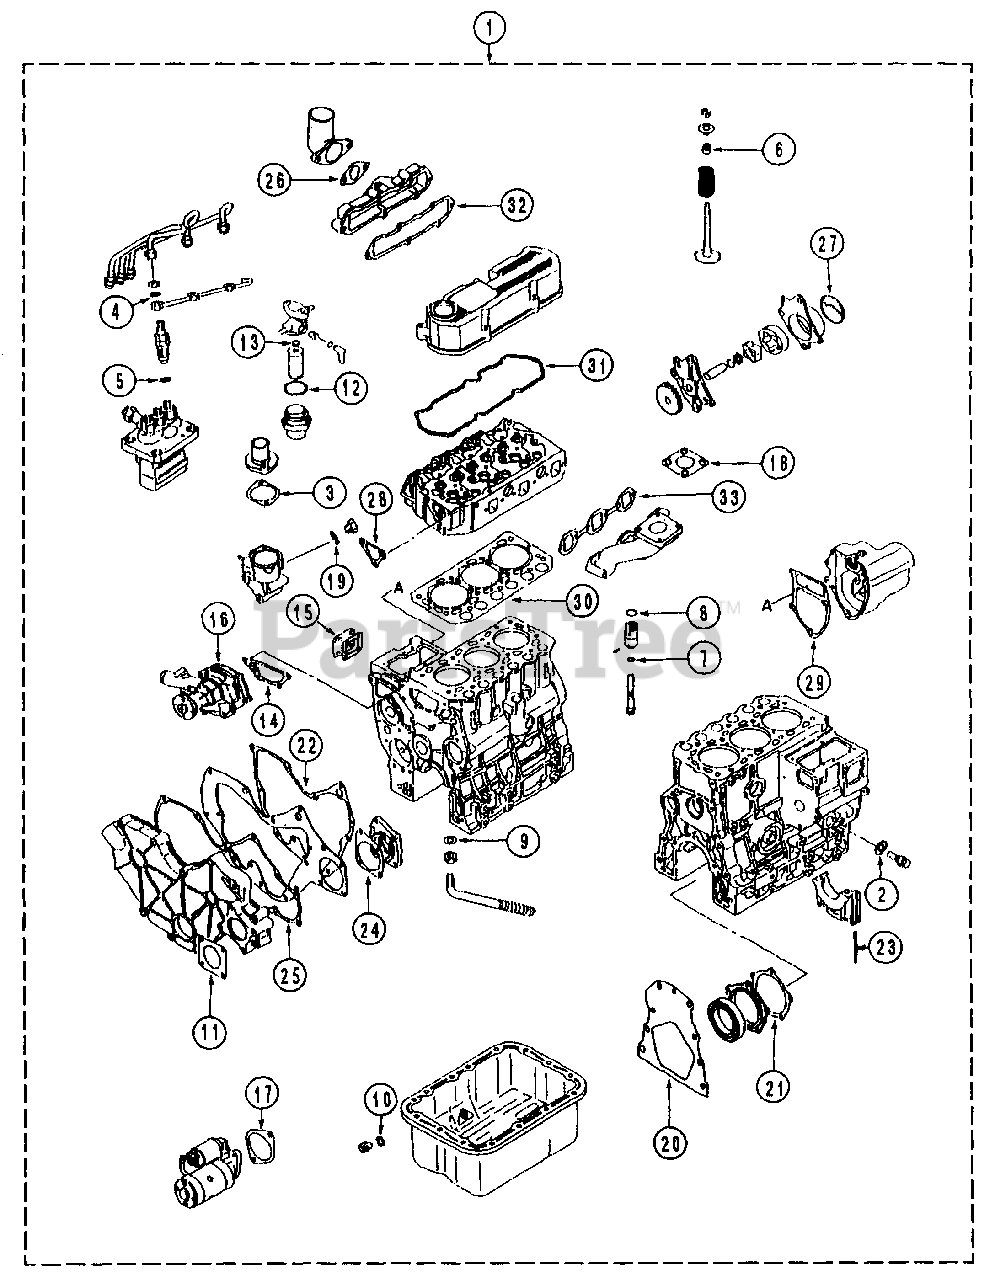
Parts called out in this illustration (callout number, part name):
1	Gasket Kit, (O/H)
3	Gasket
6	Seal, Valve Stem
8	O-Ring
11	Gasket, O/Pump Cover
12	O-Ring
13	O-Ring
14	Gasket, Water Pump
15	Gasket, Tie-Rod Cover
16	Gasket, Water Pump
17	Gasket, Starter
20	Gasket, Rear Plate
21	Gasket, Oil Seal Case
22	Gasket, Front Plate
24	Gasket, Housing
25	Gasket, Gear
26	Gasket, Inlet
27	Packing, Body
28	Gasket, Thermo Case
29	Gasket, Governor Case
30	Gasket, Cylinder Head
31	Gasket, Rocker Cover
32	Gasket, Inlet Cover
33	Gasket, Exh. Manifold
